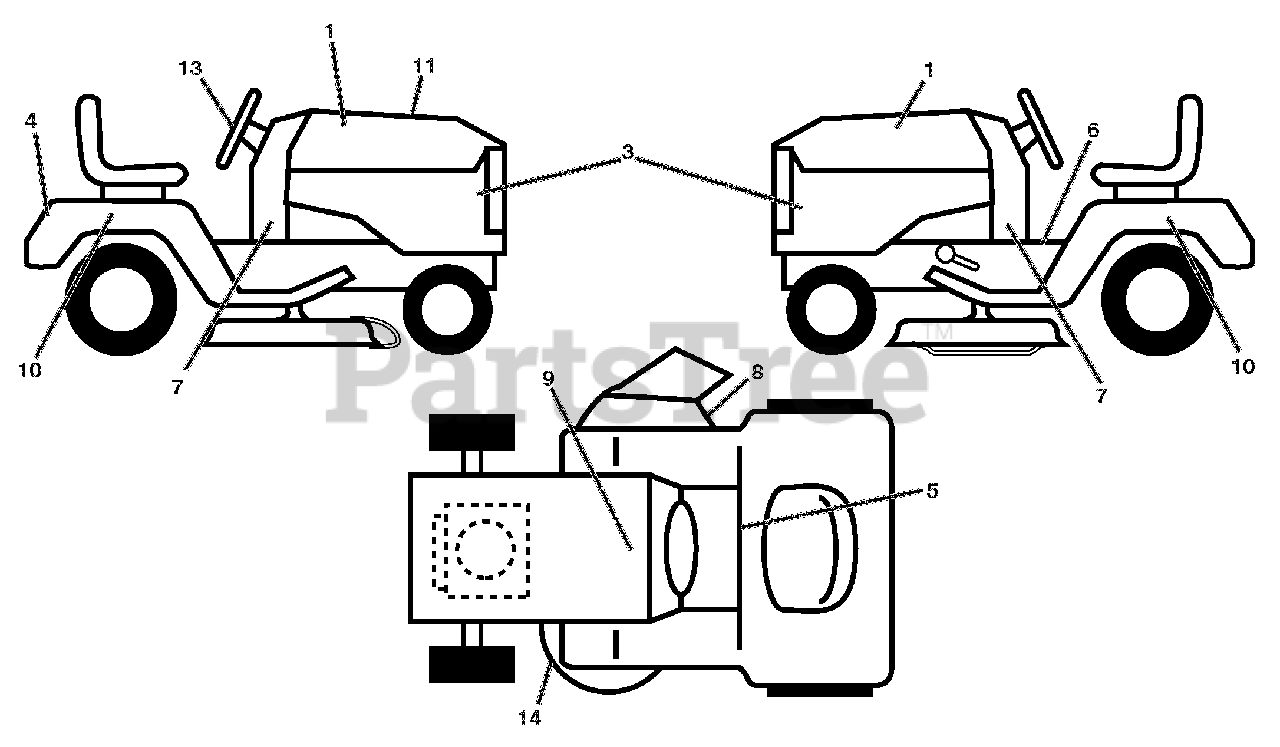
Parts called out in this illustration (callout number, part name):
1	DECAL.HOOD.RH.PRECISION.ARIENS
3	DECAL.SDPNL.PWRDBY KOHL.ARIENS
4	DECAL.FENDER.REAR.ARIENS
5	DECAL.FENDER
6	DECAL, WARNING START INST.
7	DECAL DASH LOWER
8	DECAL.MOWER.WARN.KEEP HAND AWY
9	DECAL.BAT.DAN/POI P/L SYM.WPN
10	DECAL.FENDER.SIDE.HYDRO.ARIENS
11	DECAL REPLACEMENT
13	DECAL.WHEEL.STEER.ARIENS
14	DECAL.V-BELT.SCH.42/46"MEC/ELE
